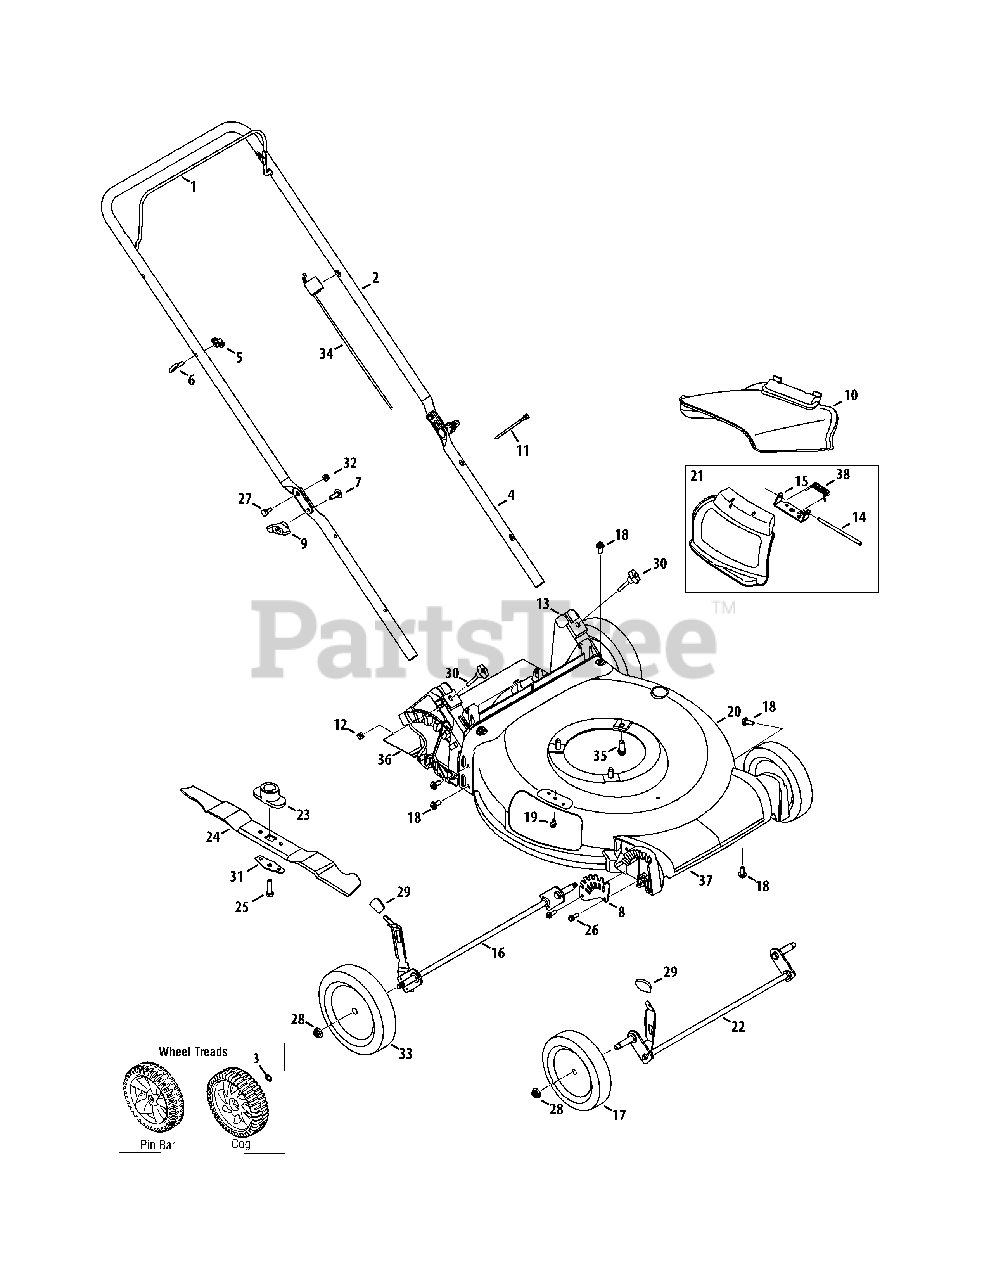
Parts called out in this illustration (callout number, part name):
1	Blade Control
2	Upper Handle
3	Wave Washer, .510 x .750 x .017
4	Lower Handle
5	Wing Nut
6	Rope Guide
7	Carriage Screw ,5/16-18
8	Front Height Adjuster Plate
9	Wing Knob
10	Side Chute
11	Cable Tie
12	Nut, Sq., 1/4-20
13	Rear Baffle
14	Hinge Pin
15	Chute Deflector Bracket
16	Rear Axle Assembly
17	Front Wheel, 7 x 1.8, Bar, Gray
17	Front Wheel, 7", Cog
18	Screw, 5/16-14 x .750
19	Screw, 1/4-20 x .500
20	Deck , 21" - Red
20	Deck , 21" -Black
21	Hinged Mulch Plug Assembly
22	Front Axle Assembly
23	Blade Adapter
23	Blade Adapter, 139cc engine
24	Mulching Blade
25	Screw , 3/8-24 x 1.50
26	Screw, 1/4-15 x .750
27	Sldr. Screw, .375 x .126 x 1/4
28	Flange Lock Nut, 3/8-16
29	Adjustment Lever Knob
30	Wing Nut
31	Blade Bell Support
32	Nut, Flange Lock, 1/4-20
33	Rear Wheel, 8 x 1.8, Bar, Gray
33	Rear Wheel, 8", Cog
34	Control Cable, 51.04", 148cc engine
34	Control Cable, 61.15", 139cc engine
34	Control Cable, 52.84" 173cc engine
35	TT Sems Screw, 3/8-16 x 1.0
36	Trail shield
37	Front Cover
38	Torsion Spring
